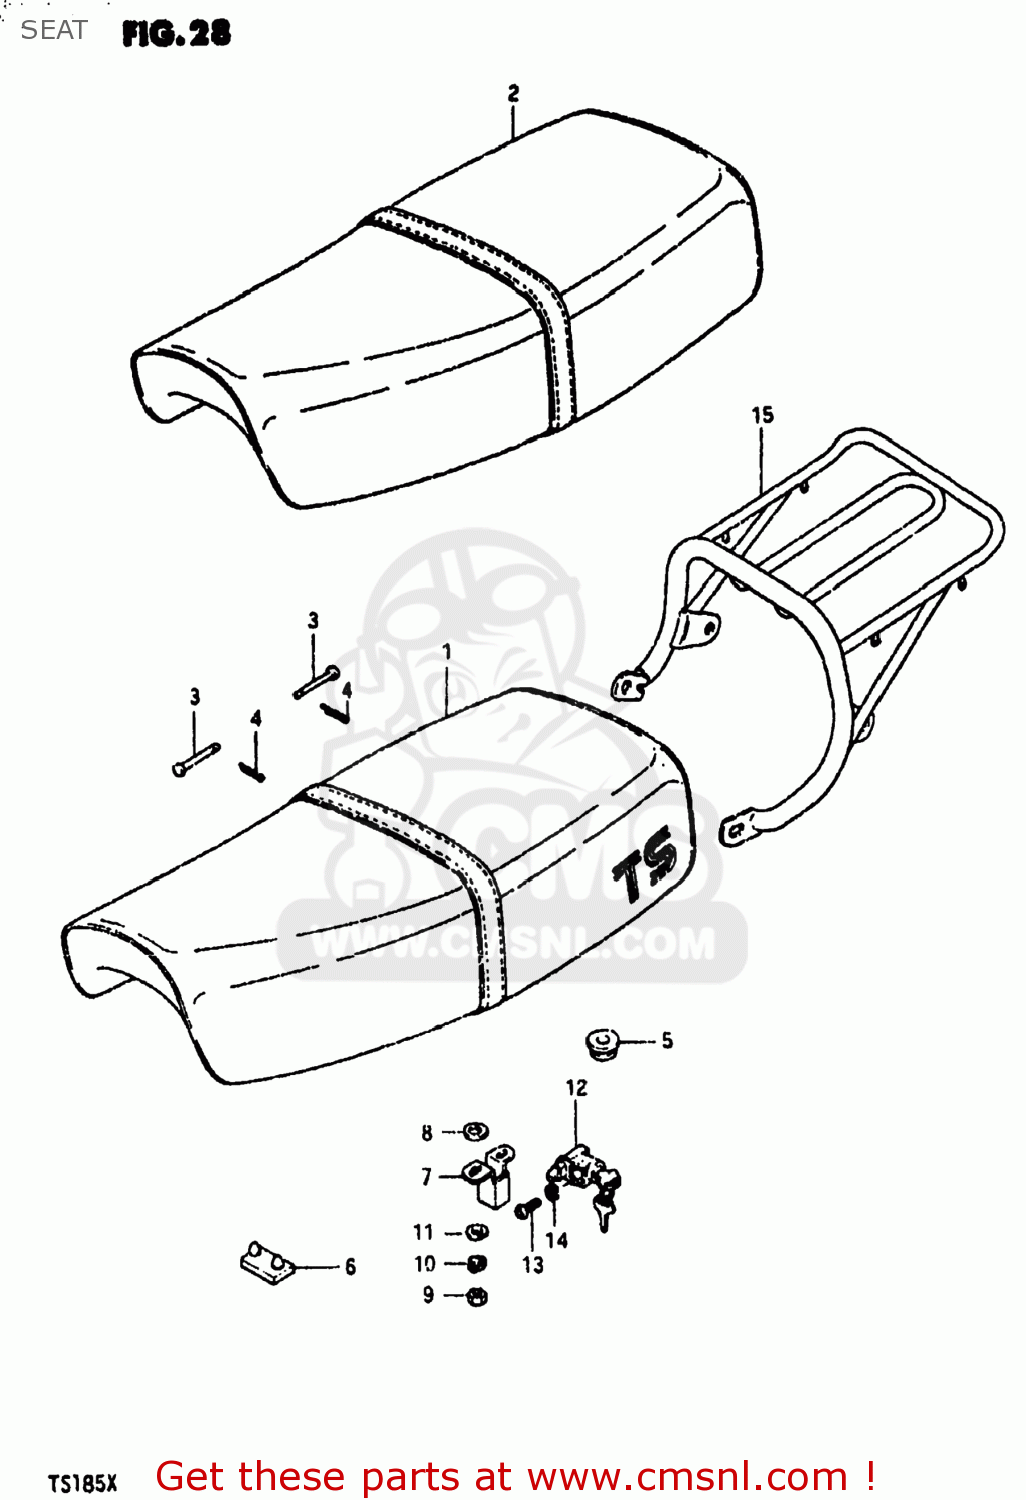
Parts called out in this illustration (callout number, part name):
1	SEAT ASSEMBLY
2	SEAT ASSEMBLY
3	PIN
4	PIN
5	CUSHION
6	CUSHION
7	PLATE,CLAMP GUIDE
8	WASHER(8.5X18X1)
9	NUT
10	LOCK WASHER
11	WASHER
12	LOCK ASSY,SEAT
13	SCREW
14	LOCK WASHER
15	CARRIER,SPORT
